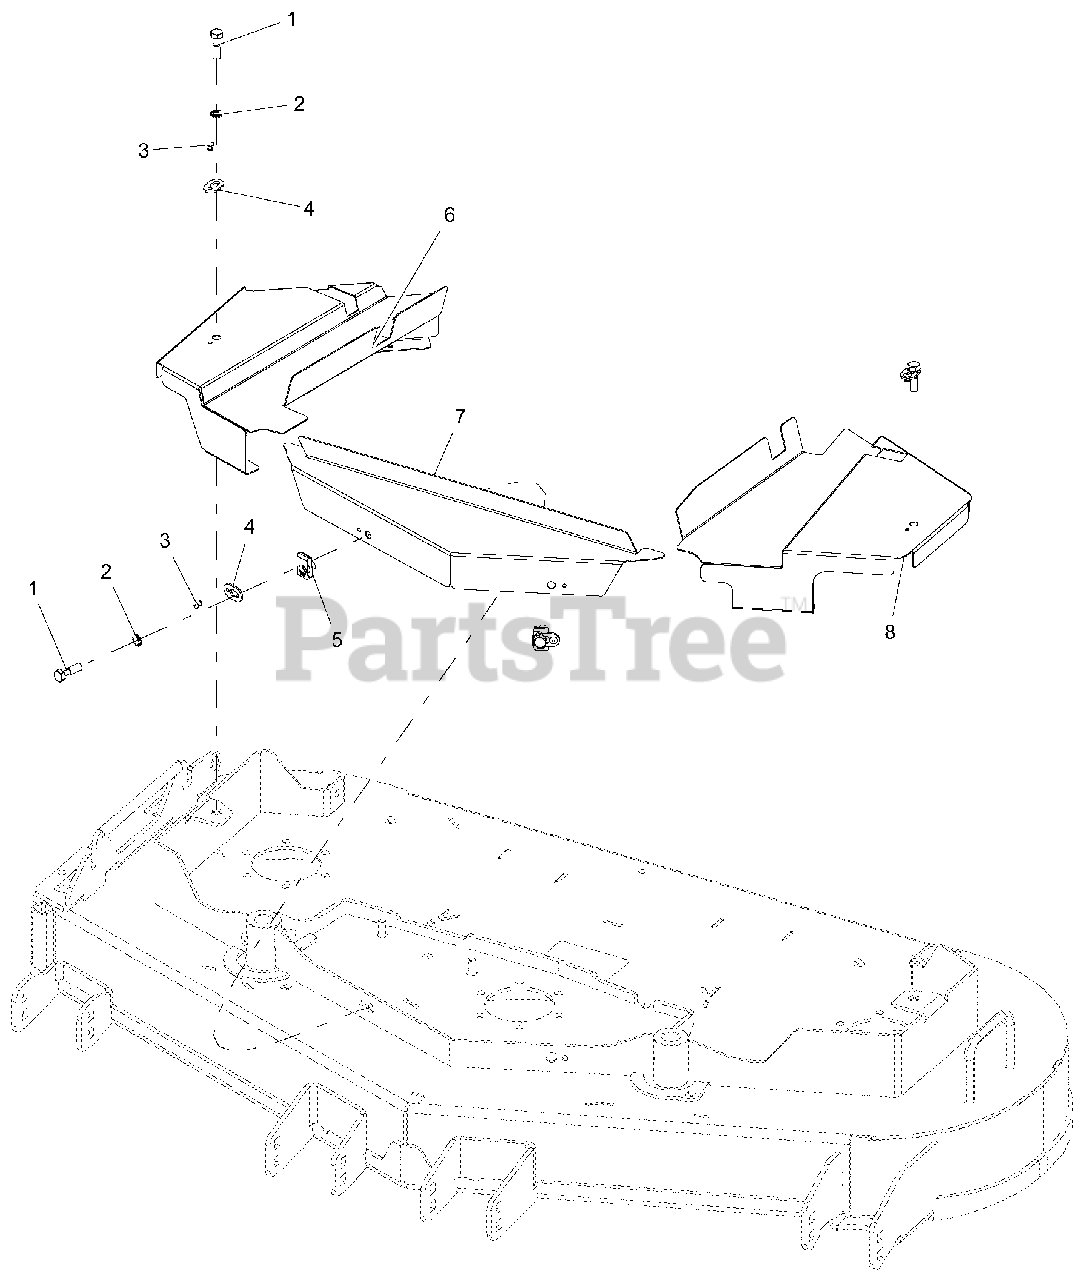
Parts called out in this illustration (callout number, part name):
1	BLT, HEX 0.38-16 X 1.25 GR5 CAPTIVE
2	LOCK, WSHR-EXT 0.391 X 0.628 X 0.036 YWZC
3	RVT-POP .187x.250 (#64) YWZC
4	KEEPER, BOLT
5	NUT, RTNR .375-16X.37
6	GUARD, BELT 52" RH (CE)-RED
7	GUARD, BELT 52" FRONT (CE)-RED
8	GUARD, BELT 52" LH (CE)-RED
